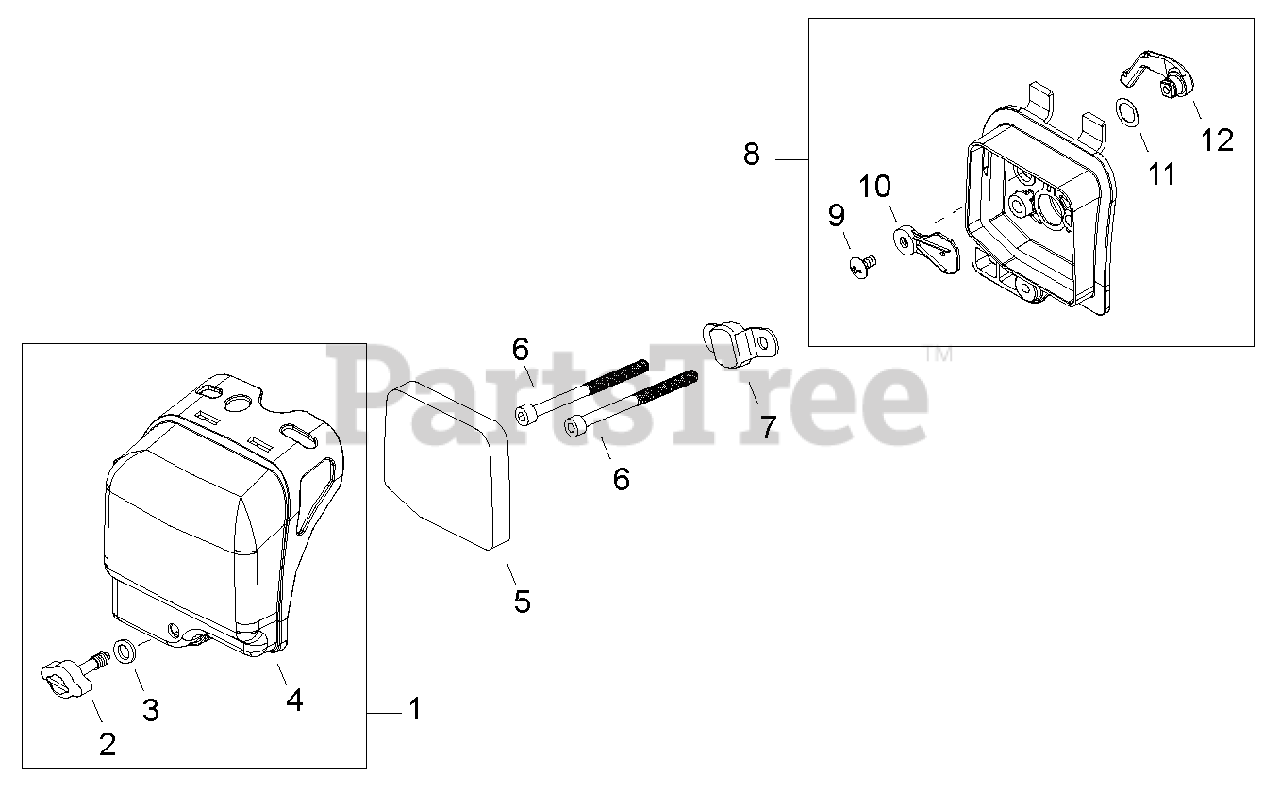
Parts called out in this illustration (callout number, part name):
2	THUMBSCREW
3	WASHER 5
4	COVER, AIR FILTER
5	FILTER, AIR
6	BOLT M5×60
7	BRACKET
8	CASE ASSY, AIR FILTER
8-1	COVER ASSY, AIR FILTER
9	SCREW, TRUSS M4×12
10	PLATE, CHOKE
11	WASHER, WAVE
12	LEVER, CHOKE
